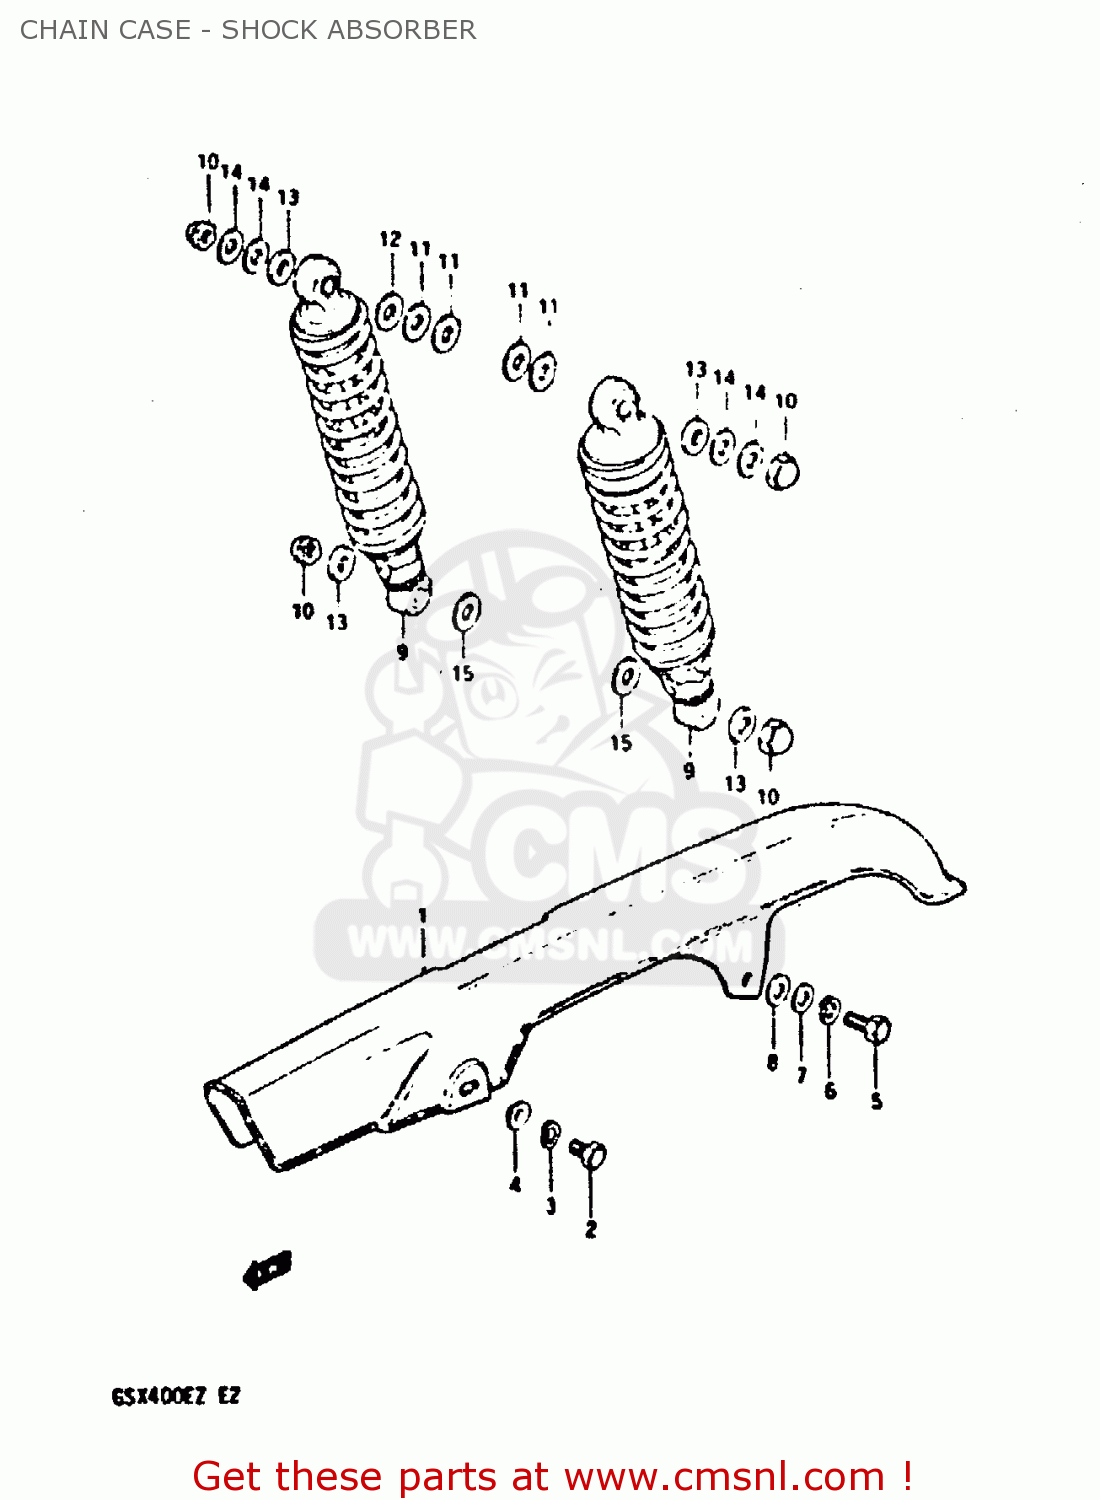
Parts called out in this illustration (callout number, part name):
1	CASE,CHAIN
2	BOLT
3	LOCK WASHER
4	WASHER,LOCK
5	BOLT
6	LOCK WASHER
7	WASHER
8	WASHER
9	SHOCK ABSORBER, REAR
10	NUT, LOWER LH
11	WASHER
12	WASHER (12.5X24X3.2)
13	WASHER
14	WASHER(10.5X24X3.2)
15	WASHER (12.5X24X1.6)
